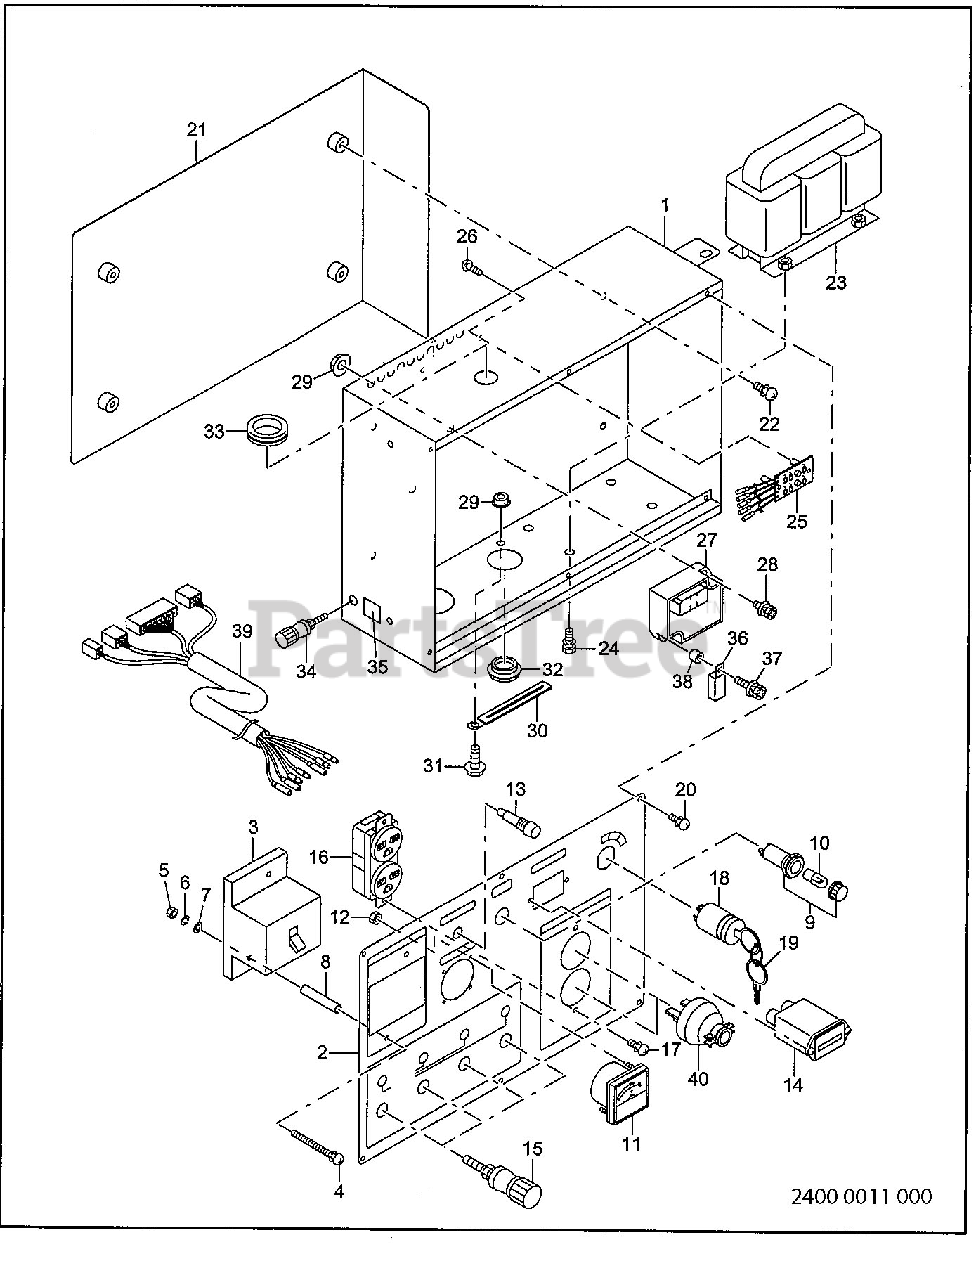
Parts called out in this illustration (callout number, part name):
1	CONTROL BOX ASSY
2	CONTROL PANEL ASSY
2	CONTROL PANEL
3	BREAKER (24A)
3	BREAKER (12A)
4	SCREW
8	SPACER
9	LAMP (OIL)
10	LAMP (18V-0.11A)
11	VOLTMETER (0-240V)
11	VOLTMETER (0-600V)
14	HOUR METER
15	TERMINAL
16	AC RECEPTACLE (250V-15A)
17	SCREW and WASHER ASSY
18	KEY SWITCH
20	SCREW and WASHER ASSY
21	PLATE
22	SCREW and WASHER ASSY
23	CURRENT TRANS
24	SCREW and WASHER ASSY
26	SCREW and WASHER ASSY
27	ECU (O/S & R/C) ASSY
28	SCREW and WASHER ASSY
29	FLANGE NUT
31	FLANGE BOLT
37	SCREW
40	AC PLUG (250V-15A)
